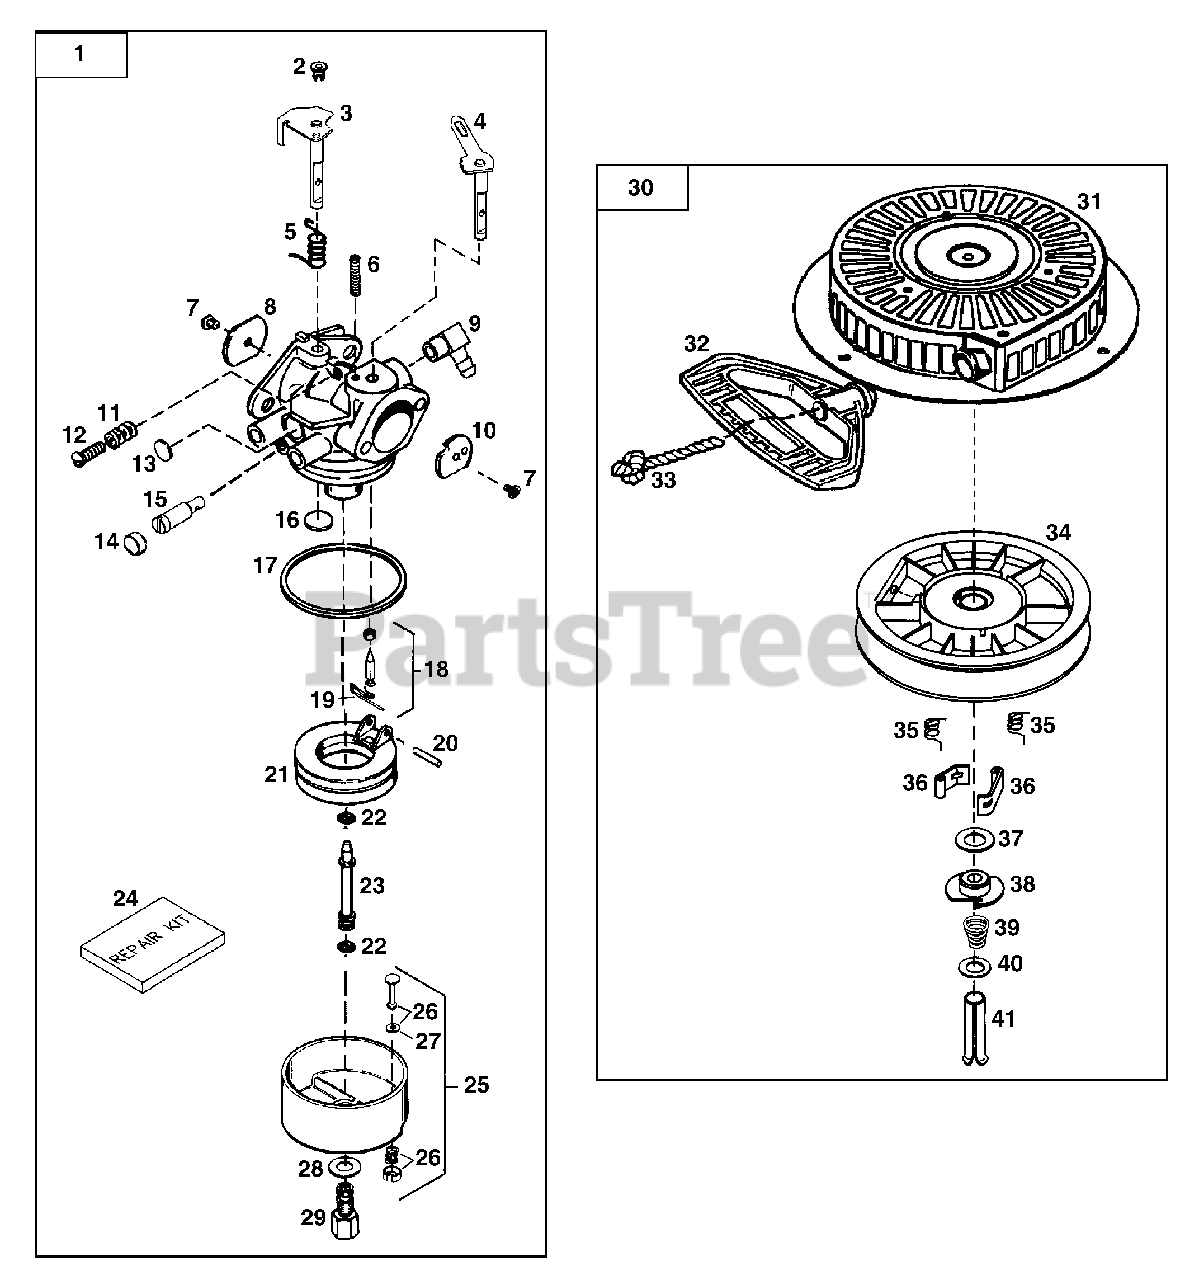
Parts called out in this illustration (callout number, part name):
1	Carburetor Assembly
2	Throttle Link Bushing
3	Throttle Shaft & Lever Assembly
4	Choke Shaft & Lever Assembly
5	Throttle Return Spring
6	Choke Positioning Spring
7	Shutter Screw
8	Throttle Shutter
9	Fuel Fitting
10	Choke Shutter
11	Tension Spring
12	Throttle Crack Screw/Idle Speed Screw
13	Welch Plug, Idle Mixture Well
14	Idle Restrictor Screw Cap
15	Idle Restrictor Screw
16	Welch Plug, Atmospheric Vent
17	Float Bowl "O" Ring
18	Inlet Needle, Seat & Clip
19	Spring Clip
20	Float Shaft
21	Float
22	"O" Ring, Main Nozzle Tube
23	Main Nozzle Tube
24	Repair kit
25	Float Bowl Assembly
26	Bowl Drain Assembly
27	Drain Plunger Gasket
28	Bowl Nut Washer
29	High Speed Bowl Nut
30	Rewind Starter
31	Starter Housing Assembly
32	Mitten Grip Handle
33	Starter Rope
34	Pulley & Rewind Spring Assembly
35	Dog Spring
36	Starter Dog
39	Brake Spring
41	Spring Pin
